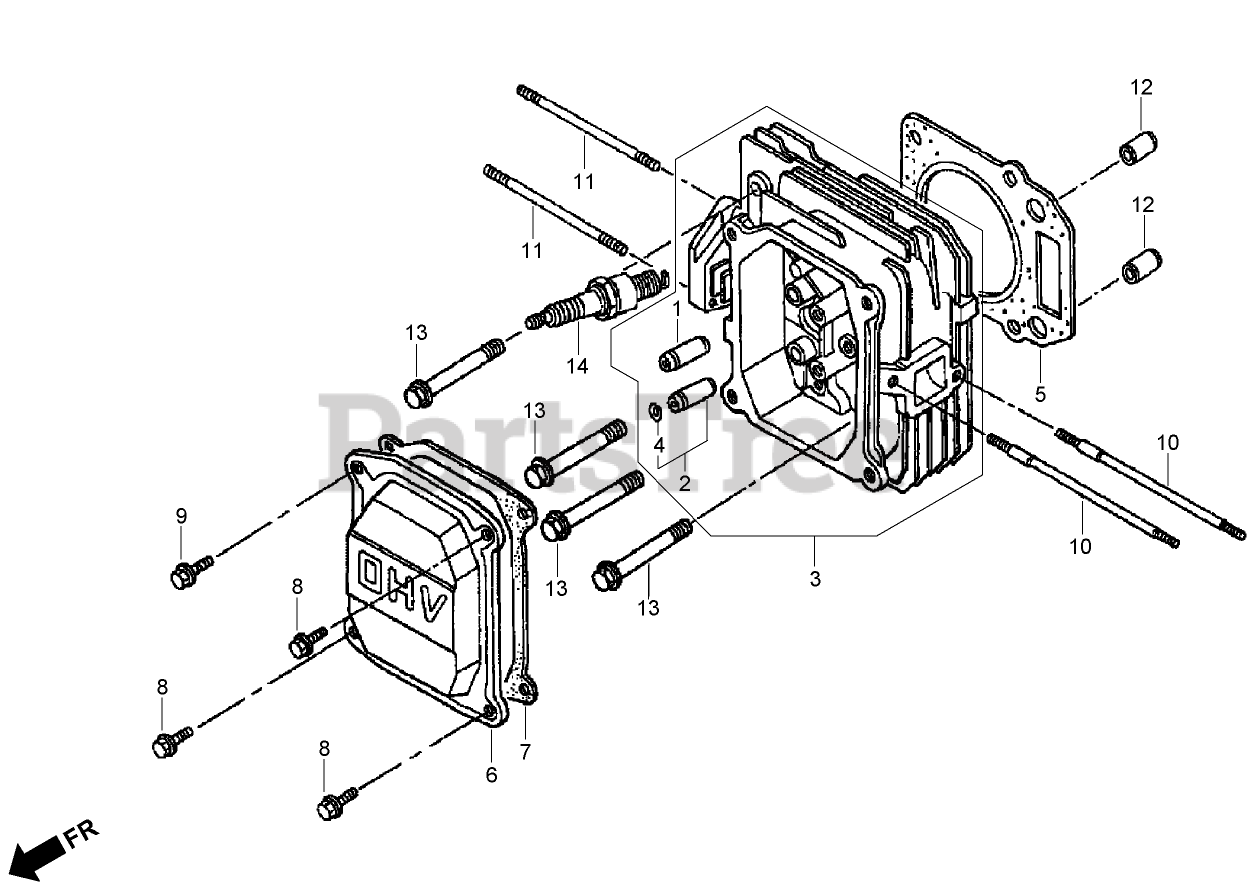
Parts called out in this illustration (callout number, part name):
1	GUIDE-VALVE (O S)
2	GUIDE-VALVE, EXHAUST (O S)
3	HEAD-CYLINDER
4	CLIP-GUIDE, VALVE
5	GASKET-HEAD, CYLINDER
6	Cover-Head
7	GASKET-COVER, CYLINDER HEAD
8	BOLT-FLANGE (6X14) (C T200)
9	BOLT-FLANGE (6X14) (C T200)
10	BOLT-STUD (6X109)
11	BOLT-STUD (6X85)
12	PIN-DOWEL (10X16)
13	BOLT-FLANGE (8X50)
14	SPARK PLUG (B P R4E S) (N G K)
14	SPARK PLUG (W14E P R-U) (DENSO)
14	SPARK PLUG (B P R 5E S) (N G K)
14	SPARK PLUG (W16E P R-U) (DENSO)
14	SPARK PLUG (B P R 6E S) (N G K)
14	SPARK PLUG (W20E P R-U) (DENSO)
